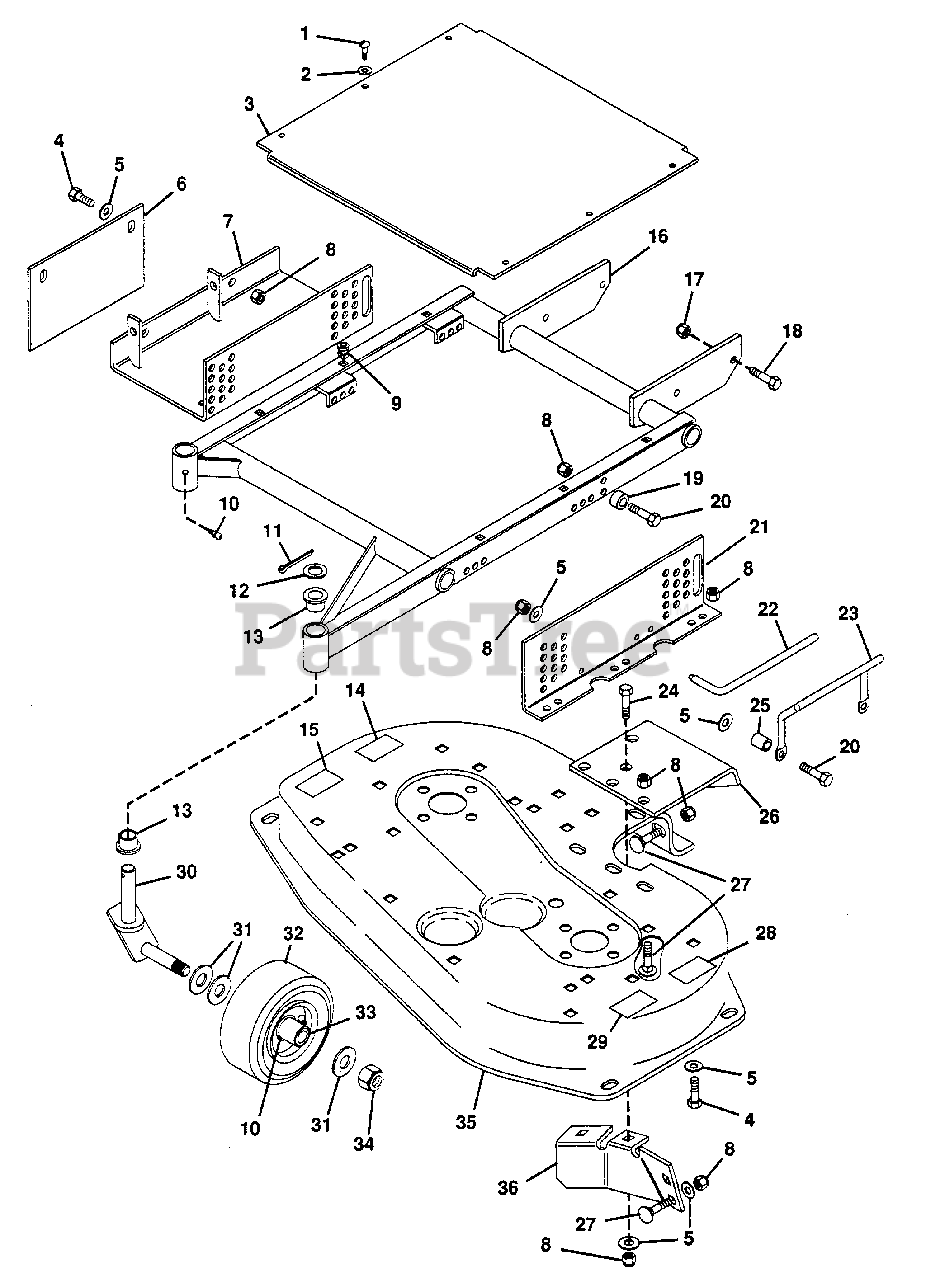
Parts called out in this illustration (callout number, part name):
1	Screw, 1/4-20x.50 Self Tapping
2	Washer, Flat .281x.625x.065
3	Cover, Silkscreen 40" Mower
4	Bolt, Hex 3/8-16x1.00
5	Washer, Flat .406x.812x.065
6	Plate, Discharge Cover
7	Weldment, Mower Support Brkt.
8	Nut, Lock 3/8-16
9	Grommet, Plastic
10	Fitting, Lube 1/4-28
11	Pin, Cotter .187x1.50
12	Race, Bearing Thrust
13	Bushing, Flange Nylon
14	Decal, Caution
15	Decal, Danger Foot
16	Weldment, Mower Frame
17	Nut, Lock 5/8-11
18	Bolt, Hex 5/8-11x1.50
19	Bushing, St. .391x.621x.676 Stl.
20	Bolt, Hex 3/8-16x1.50
21	Bracket, Mower Side Support R.H.
22	Pin, Mower Locking
23	Handle
24	Bolt, Hex 3/8-16x1.25
25	Bushing
26	Shield, Discharge
27	Bolt, 3/8-16x1.00 Rd Hd Sq Nk
28	Decal, Warning Eye
29	Decal, Danger Hand
30	Weldment, Caster Fork
31	Washer,Flat .812x1.496x.134
32	Wheel, Gauge
33	Bearing, Gauge Wheel
34	Nut, Lock 3/4-10
35	Deck, 40" Mower
36	Shroud, Blade
